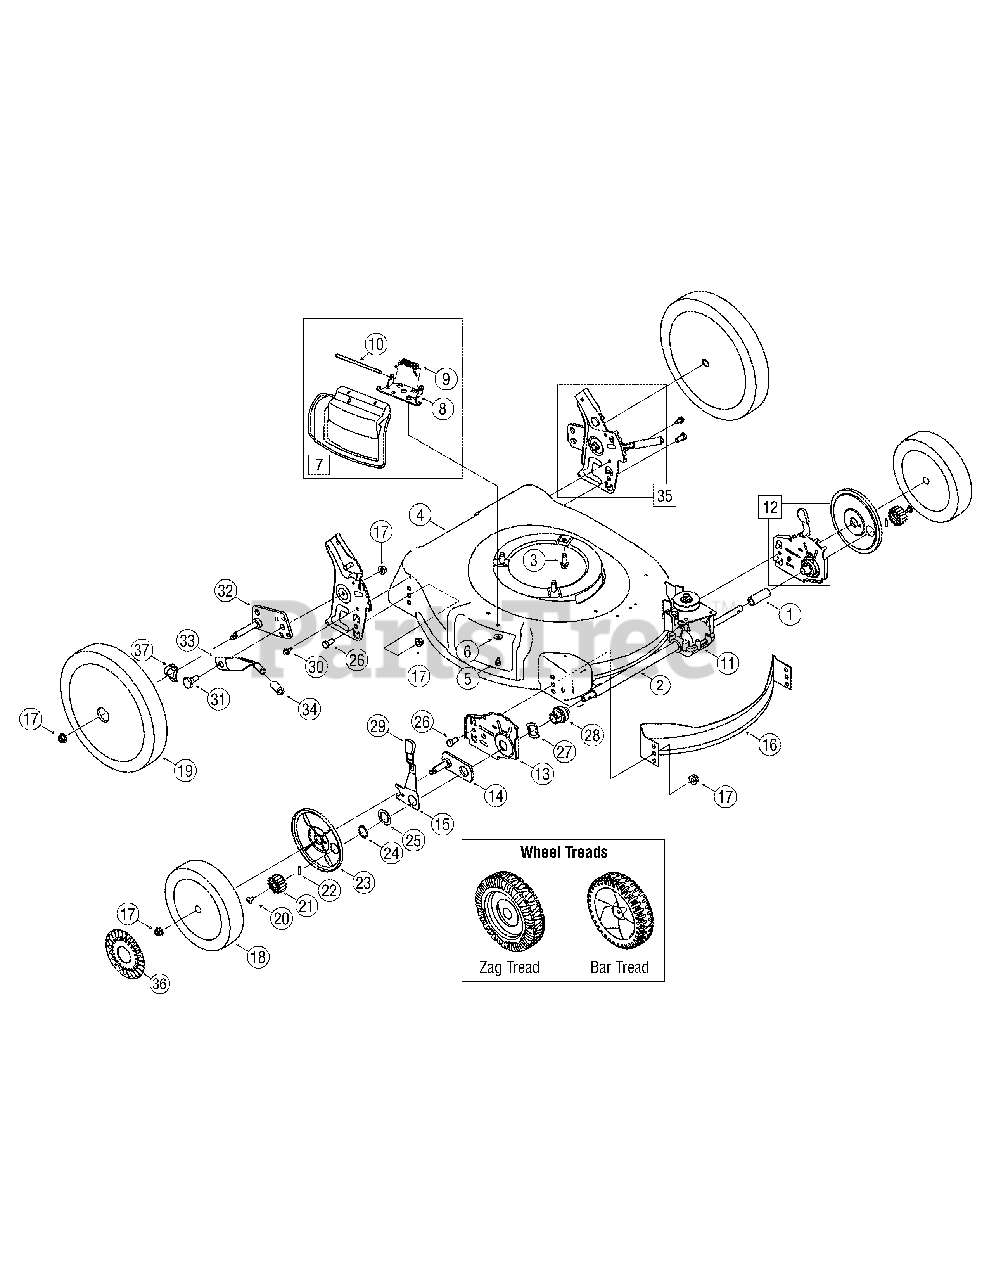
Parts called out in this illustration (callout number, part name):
1	Slev. Spacer 1.8" Lg.
2	Sleeve Spacer 9.10" Lg.
3	Self-Tapping Sems Screw
7	Hinged Mulch Plug Assembly
8	Chute Deflector Adapter
9	Torsion Spring
10	Hinge Pin
11	Transmission Assembly
12	Height Adj. Assembly - LH
13	Front Height Adj. Plate - RH
14	Pivot Plate Assembly
15	Front Lever - RH
16	Front Baffle
17	Flange Lock Nut, 3/8-16
18	Front Wheel, 8 x 2.125, Zag
19	Rear Wheel, 12 x 2.125, Zag
20	Screw 1/4-20 x .390
21	Gear 14T RH FWD RH
22	Dowel Pin
23	Wheel Dust Cap
26	Hex Screw, 3/8-16 x.75
28	Bearing Assembly
29	Adjustment Knob
30	TT Scr. w/Washer 1/4-20 x.625
31	Shoulder Scr.500 Dia. x.434
32	Pivot Arm Assembly - RH
33	Rear Spring Lever
35	Handle Bracket Assembly - LH
36	Hub Cap
37	Washer, Sprg, .500 x 1.00 x .022
